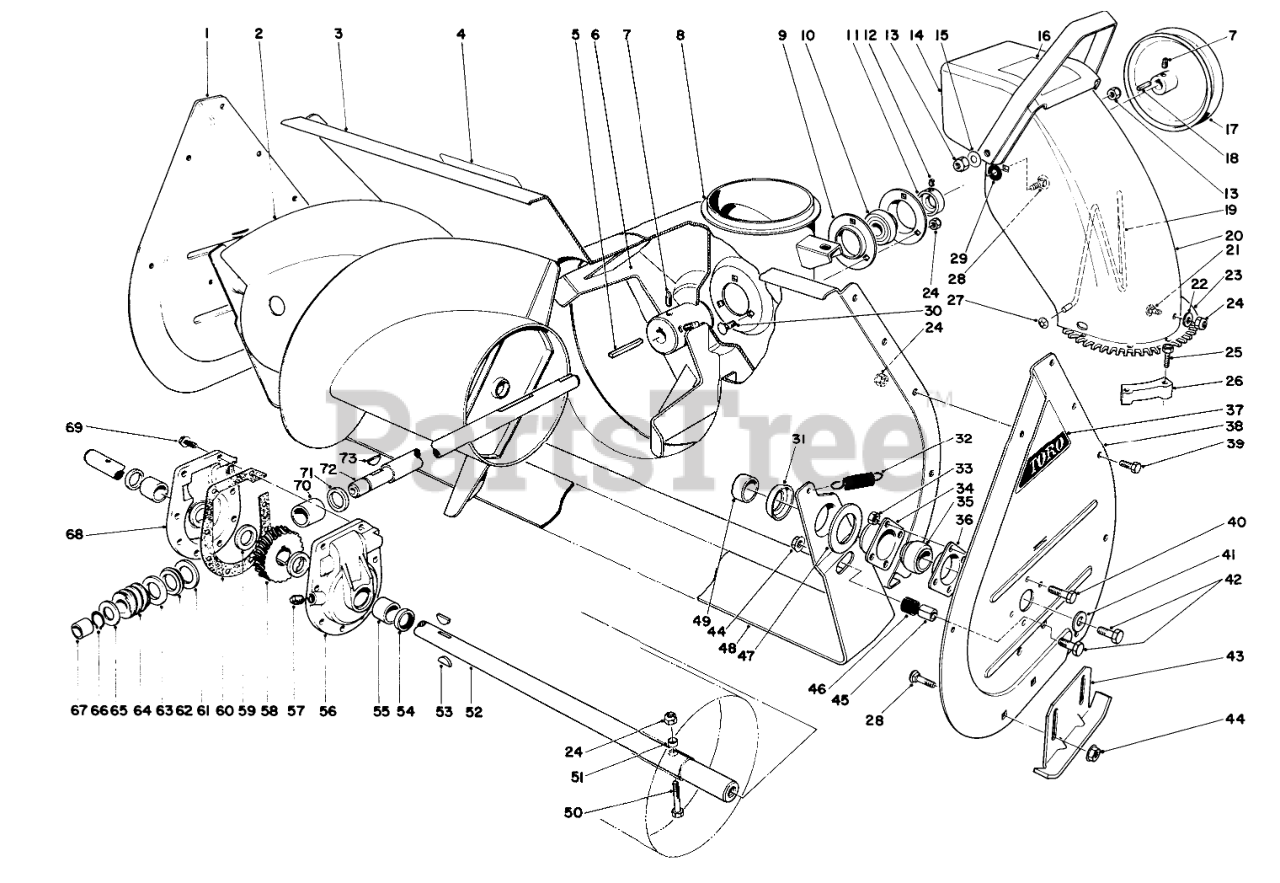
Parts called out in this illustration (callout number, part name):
1	RH AUGER SIDE PLT R
2	RH AUGER WA 26" B
3	AUGER HSG WA 26" R
4	Decal-Warning
6	IMPELLER ASM
7	SCREW-SET, SQH
8	CHUTE RING
9	BRG FLANGE
10	BALL BRG W/COLLAR
11	EXT LOCKING COLLAR
12	SCREW-HSH
13	NUT-LOCK, CONE
14	Deflector (Incl. Ref. #16)
15	WASHER-BELLEVILLE
16	Decal-Danger
17	1/2 X 9.5 DIA PULLEY
18	SQUARE KEY
19	WIRE-CHUTE
20	Upper Chute
21	SCREW-CARR
22	WASHER-PLAIN
23	Screw
24	NUT-LOCK, NI
25	SCREW-SPECIAL
26	RETAINER-CHUTE
27	NUT-PUSH
28	SCREW-CARR
29	WASHER-RUBBER
30	BOLT-CARR
31	Positioner-Scraper
32	SPRING-TENSION
33	NUT-LOCK, CONE
34	BEARING-FLANGE, FRONT
35	BEARING
36	BEARING-FLANGE, REAR
37	AUGER SIDE PLT DECAL
38	LH AUGER SIDE PLT R
39	SCREW-HH
40	SCREW-HH
41	WASHER
42	SCREW-HH
43	AUGER SKID WA R
44	Locknut
45	SCRAPER STOP SPACER
46	SCRAPER STOP CUSHION
47	SCRAPER BLADE SPACER
48	SCRAPER BLADE 26 R
49	AUGER SPACER
50	Auger Bolt
51	SPACER-HUB, AUGER
52	26 AUGER SHAFT
53	KEY-WOODRUFF
54	SEAL-OIL
55	BUSHING
56	Gear Case L.H. (Incl.Ref. #54-55)
57	PLUG-PIPE, SQH
58	GEAR-WORM, 27T
59	WASHER-THRUST
60	GASKET-CASE, GEAR
61	WASHER-THRUST
62	BEARING-THRUST
63	THRUST-WASHER
65	WASHER-THRUST
66	Snap Ring
67	BUSHING
68	Gear Case R.H. (Incl.Ref. #54-55)
69	SCREW-HWH
70	BUSHING-SPECIAL
71	RING-QUAD
72	SHAFT-IMPELLER
73	KEY-WOODRUFF
